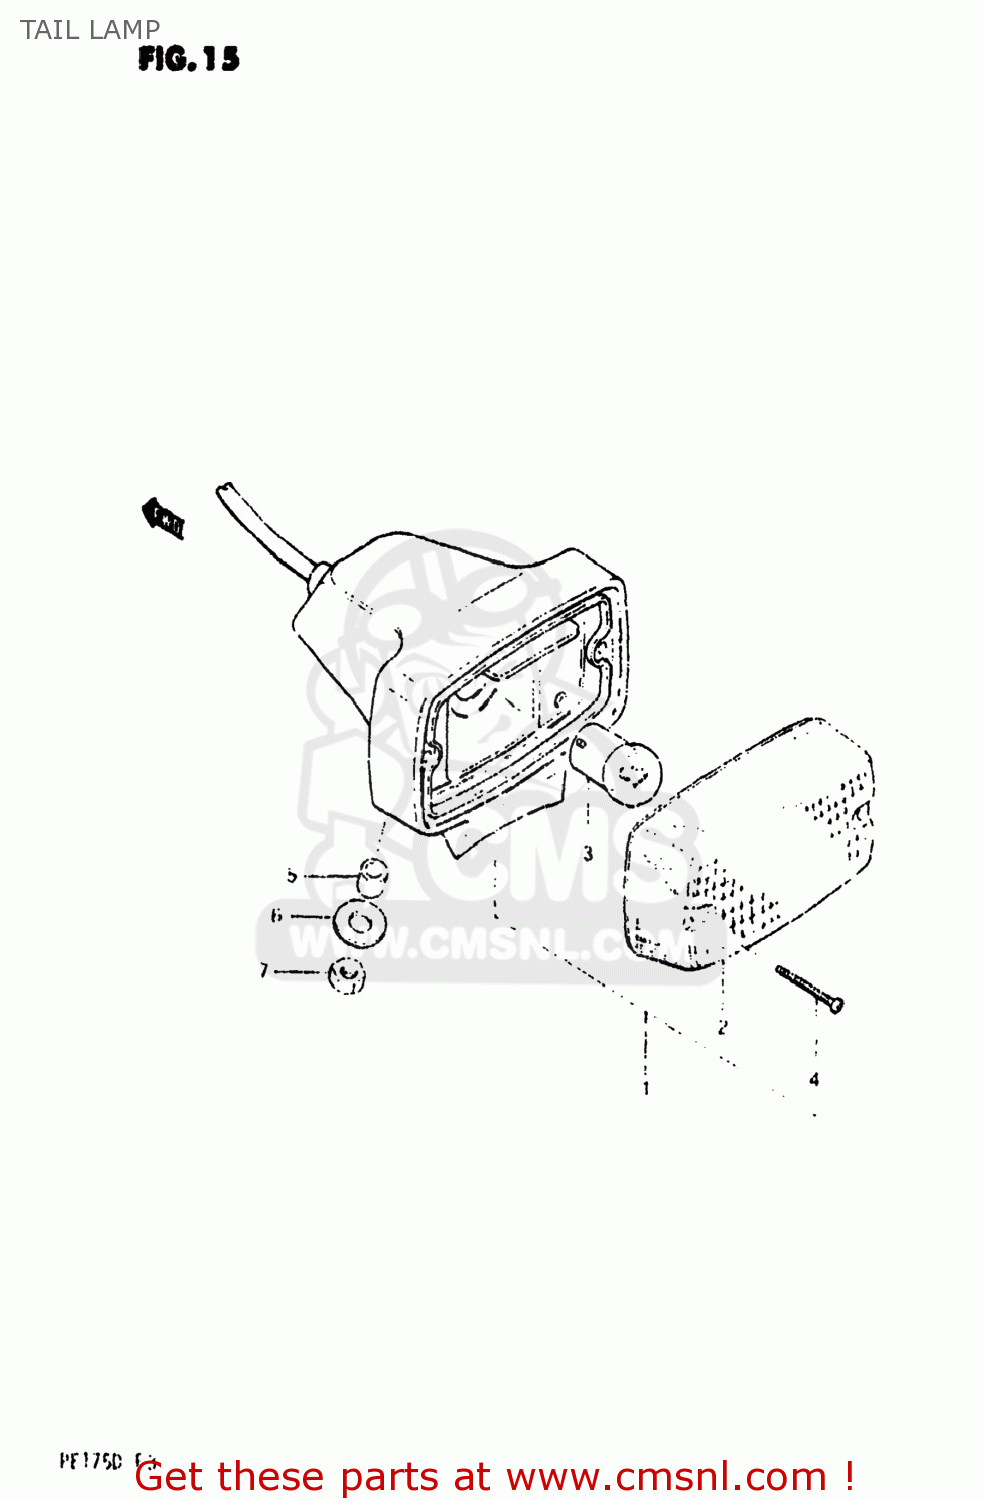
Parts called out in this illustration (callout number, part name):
1	LAMP ASSEMBLY,TAIL
2	LENS
3	BULB(6V5W,TOKAI DENSO)
4	SCREW,REAR COMBINATION LAMP LENS
5	SPACER (6.1X9X9)
6	WASHER
7	NUT
